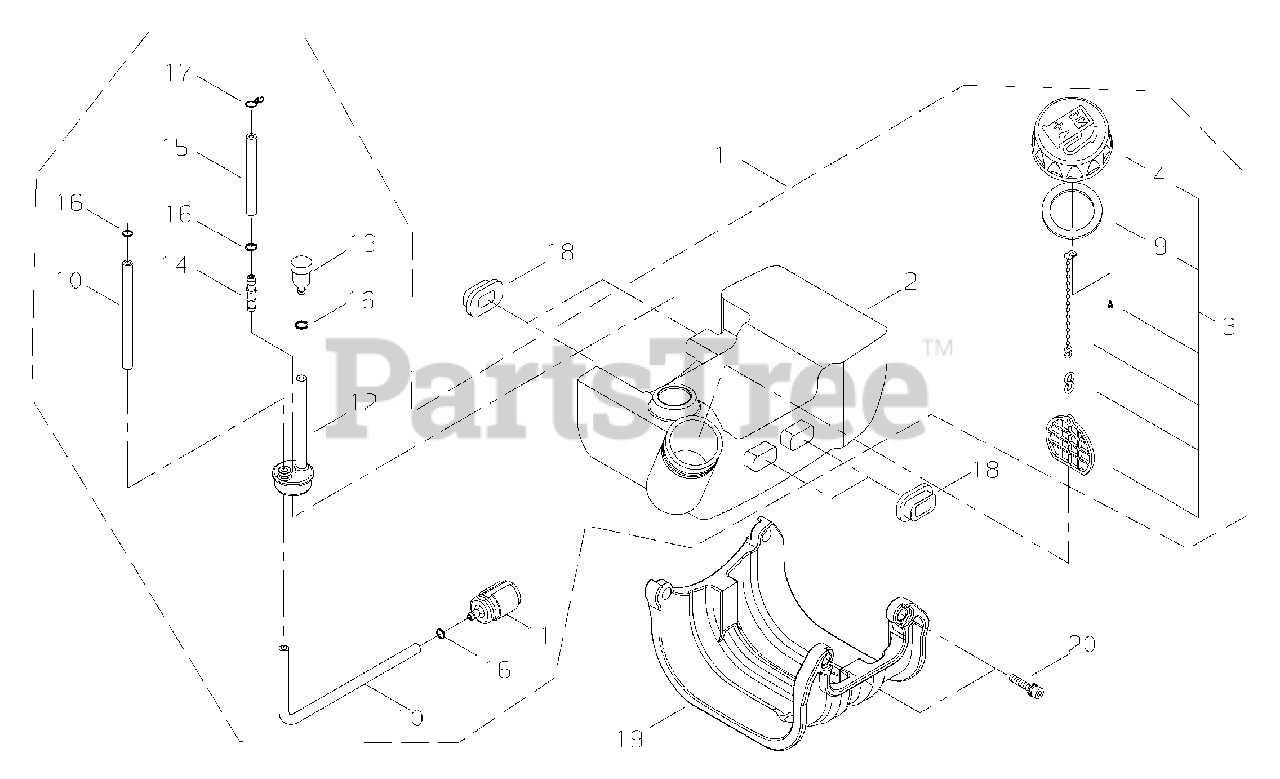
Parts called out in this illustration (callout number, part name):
1	FUEL TANK ASSY
2	TANK, FUEL
3	CAP ASSY
4	CAP, FUEL
9	GASKET, CAP
10	PIPE - FUEL
11	FILTER, FUEL
12	GROMMET
13	ELEMENT, BREATHER
14	CONNECTOR, PIPE
15	PIPE
16	RING, RETAINING - 6
17	CLIP - SPRING
18	CUSHION, FUEL TANK
19	GUARD, FUEL TANK
20	SCREW - 5X20
